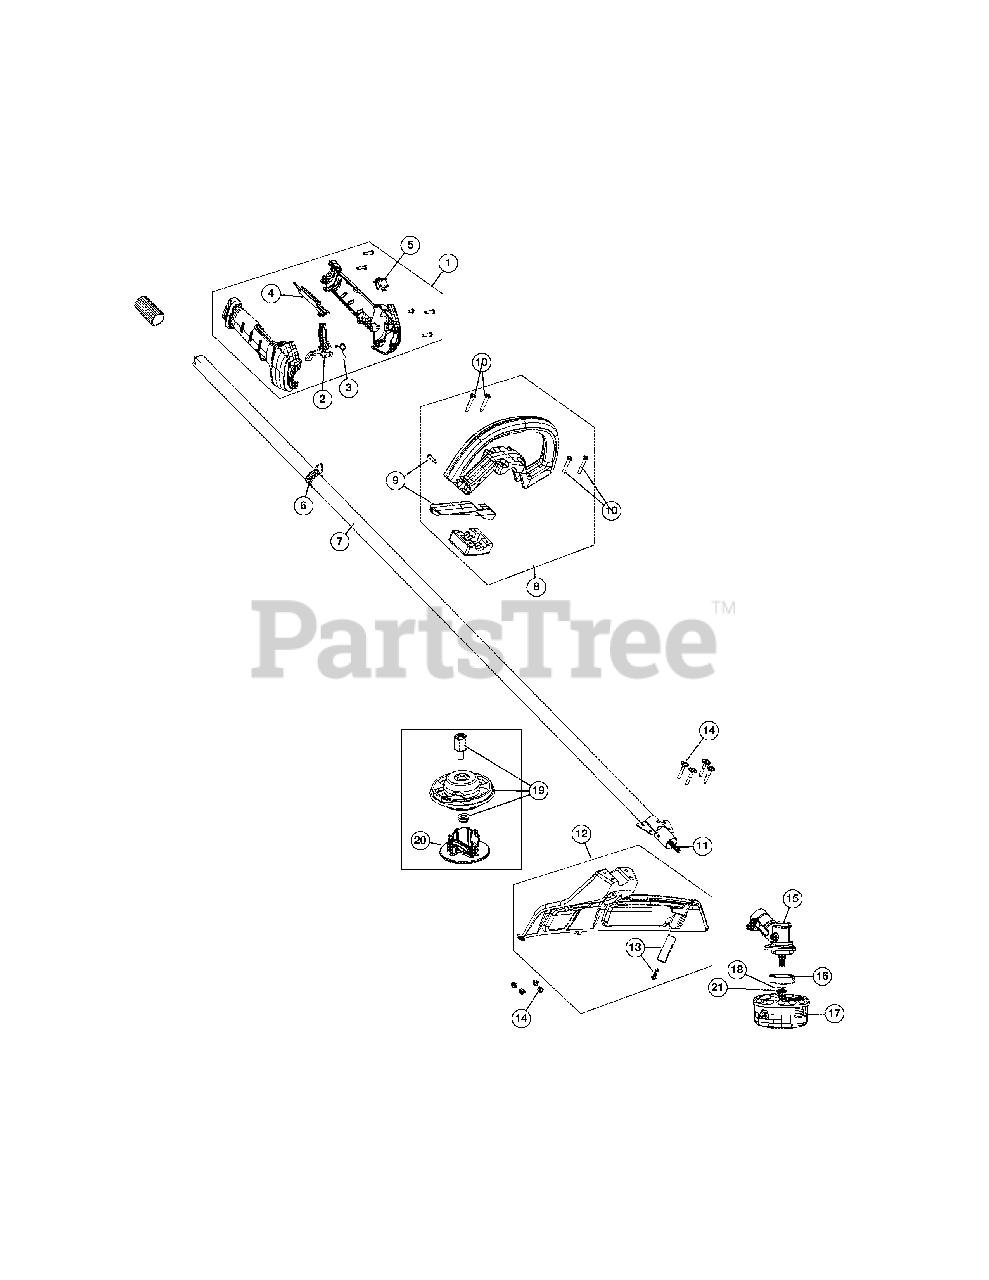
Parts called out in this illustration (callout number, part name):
1	Throttle Housing Assembly (includes 2-5)
2	Throttle Trigger
3	Spring
4	Throttle Lock-out
6	Shoulder Strap Clip
7	Driver Shaft Housing
8	D-Handle Assembly (includes 9 & 10)
9	Barrier Bar Assembly
11	Flexible Drive Shaft
12	Shield Assembly (includes 13)
13	Blade Assembly
14	Screw & Nut
15	Gearbox
16	Gearbox Spacer
17	Cutting Head Assembly
18	Palnut
19	Fixed Line Head
20	Glide Plate
21	Washer
